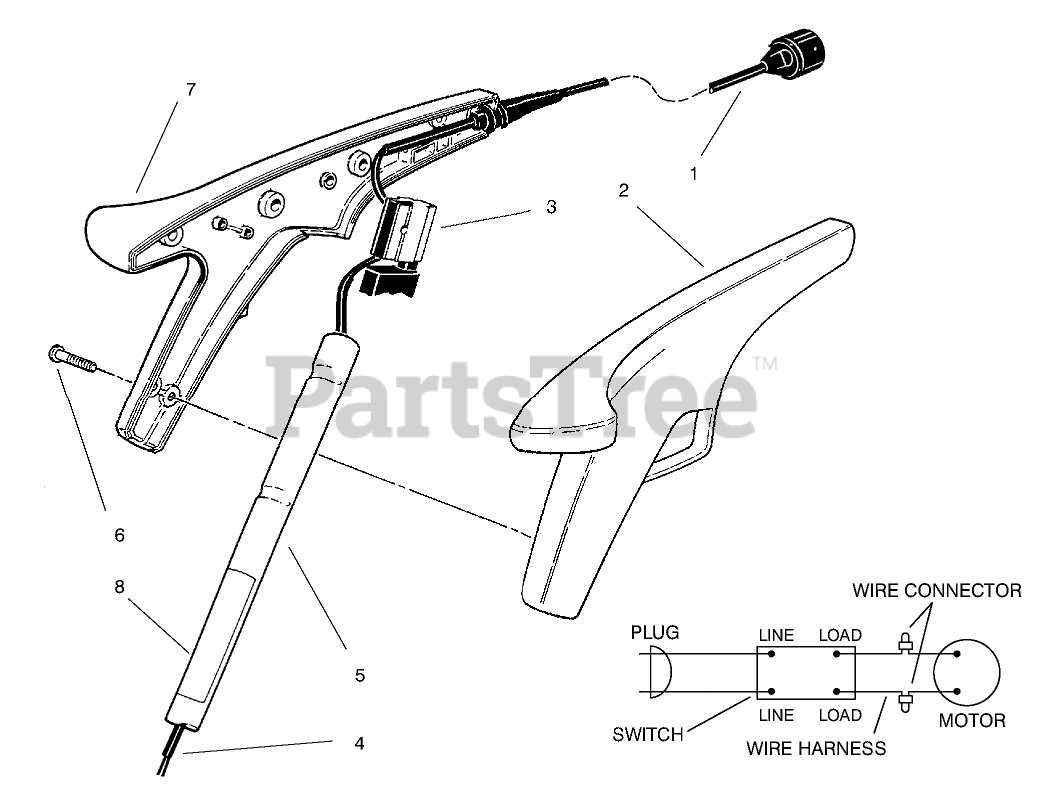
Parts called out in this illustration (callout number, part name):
1	CORD-SUPPLY
2	HAND GRIP - L.H. 8"
3	SWITCH SINGLE SPEED
4	WIRE HARNESS
5	Tube Assy. (Incl. Ref.# 8)
6	SCREW-PPH
7	HAND GRIP - R.H. 8"
8	Decal-Safety
